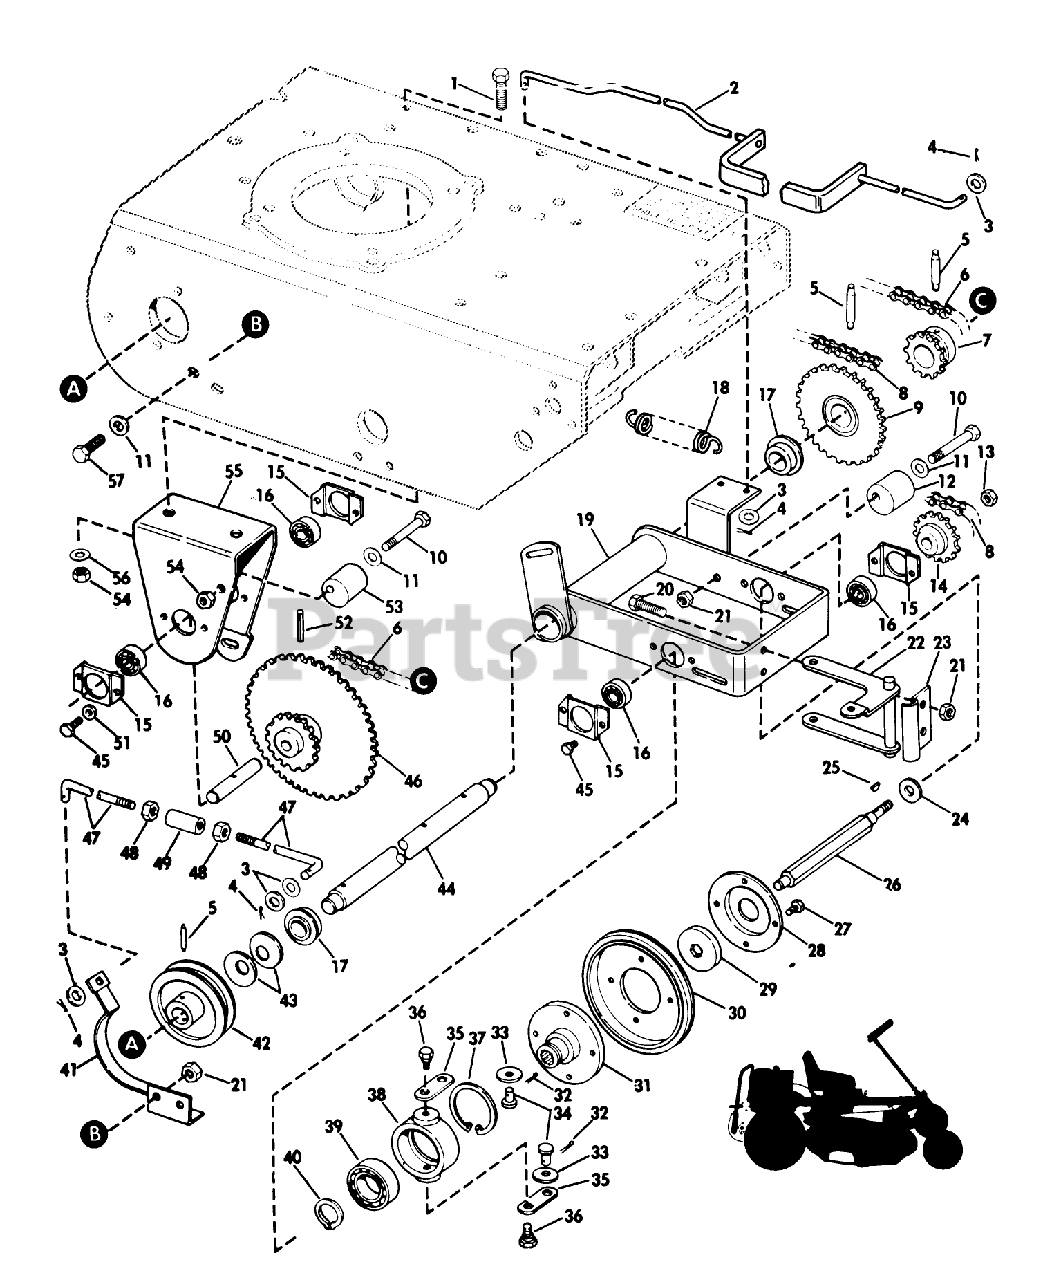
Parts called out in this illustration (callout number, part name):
13	LOCKNUT
30	DRIVE WHEEL
48	STOP NUT
54	LOCKNUT
